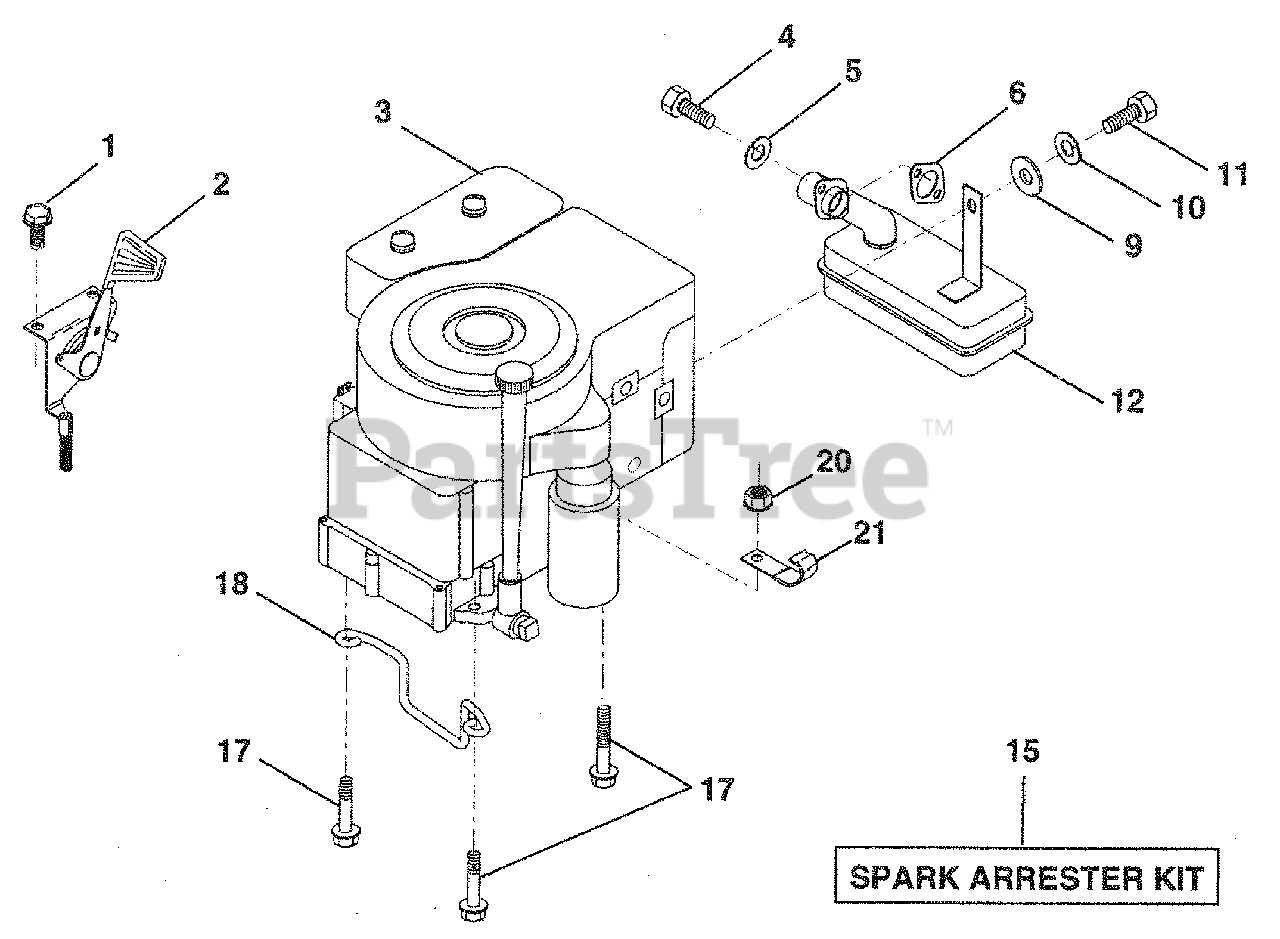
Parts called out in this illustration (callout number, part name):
1	Screw, Hex Thd. Cut 1/4-20 x 1/2
2	Control, Throttle
4	Screw, Hex, Cap 5/16-18 x 3/4
5	Washer, Lock Heavy Helical Spring 5/16
6	Gasket, Exhaust
9	Washer 5/16 x 3/4 x 16
10	Washer, Lock Heavy Hlcl Sprg 1/4
11	Bolt, Hex Fin. 1/4-20 UNC x 3/4
15	Arrester, Spark
17	Screw, Hex Washer Head, Thdrol. 3/8-16 x 1-1/2
18	Keeper, Ground Drive Beit
20	Nut, Keps 3/8 - 16
21	Clip, Fuel Line
